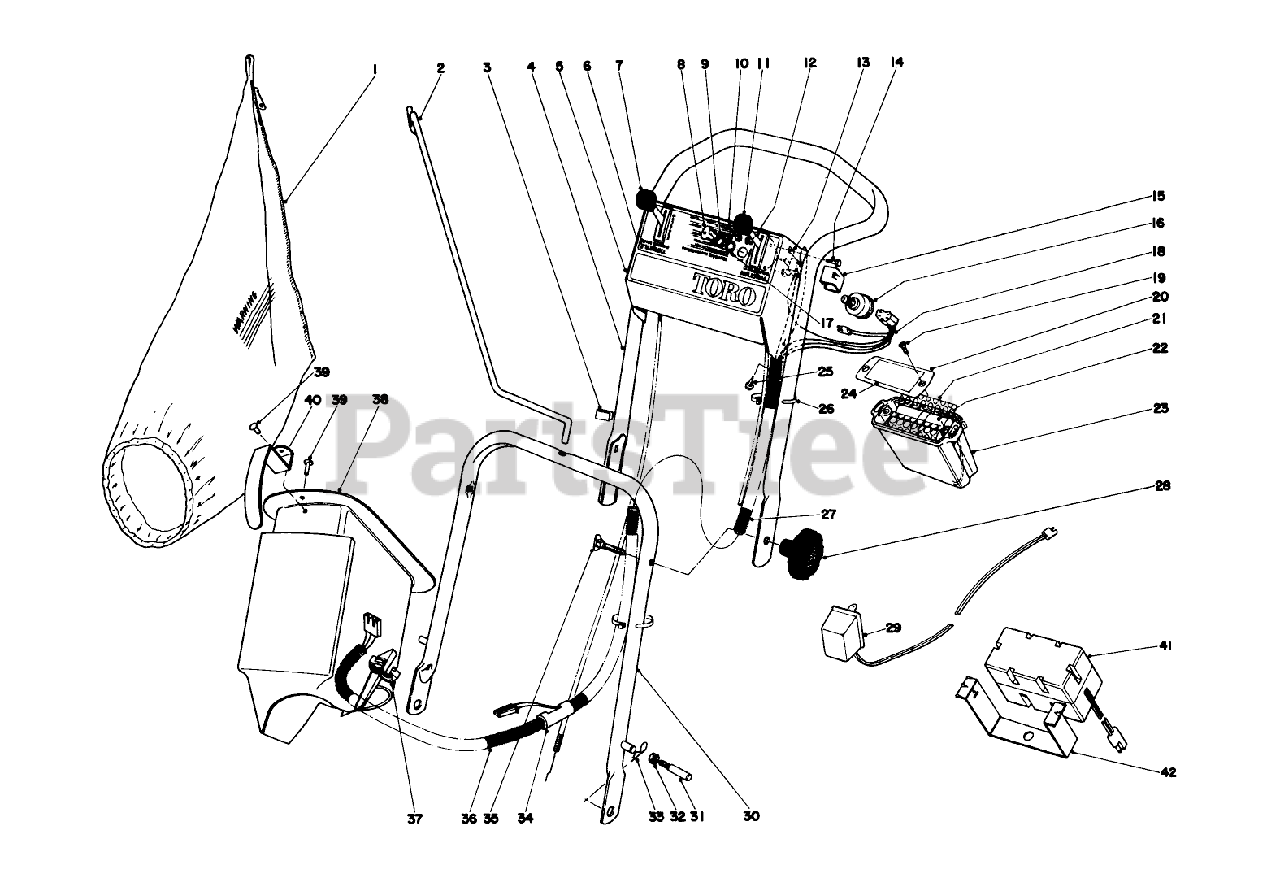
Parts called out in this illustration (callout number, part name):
3	BOWDEN CLIP
4	UPPER HANDLE
9	NUT-HH
10	NUT-HEX
12	WASHER-FLAT
13	CONTROL SWITCH
14	DISC PREC HUSKY
16	SWITCH-STARTER
17	WASHER-LOCK
25	SCREW-HWHTF
26	TIE-CABLE
31	HANDLE PIN
33	PIN-COTTER, HAIR
35	SCREW-HANDLE
37	RING FITTING
39	RIVET 3/16 X 7/16
40	Handle Chute
41	Battery Gates
